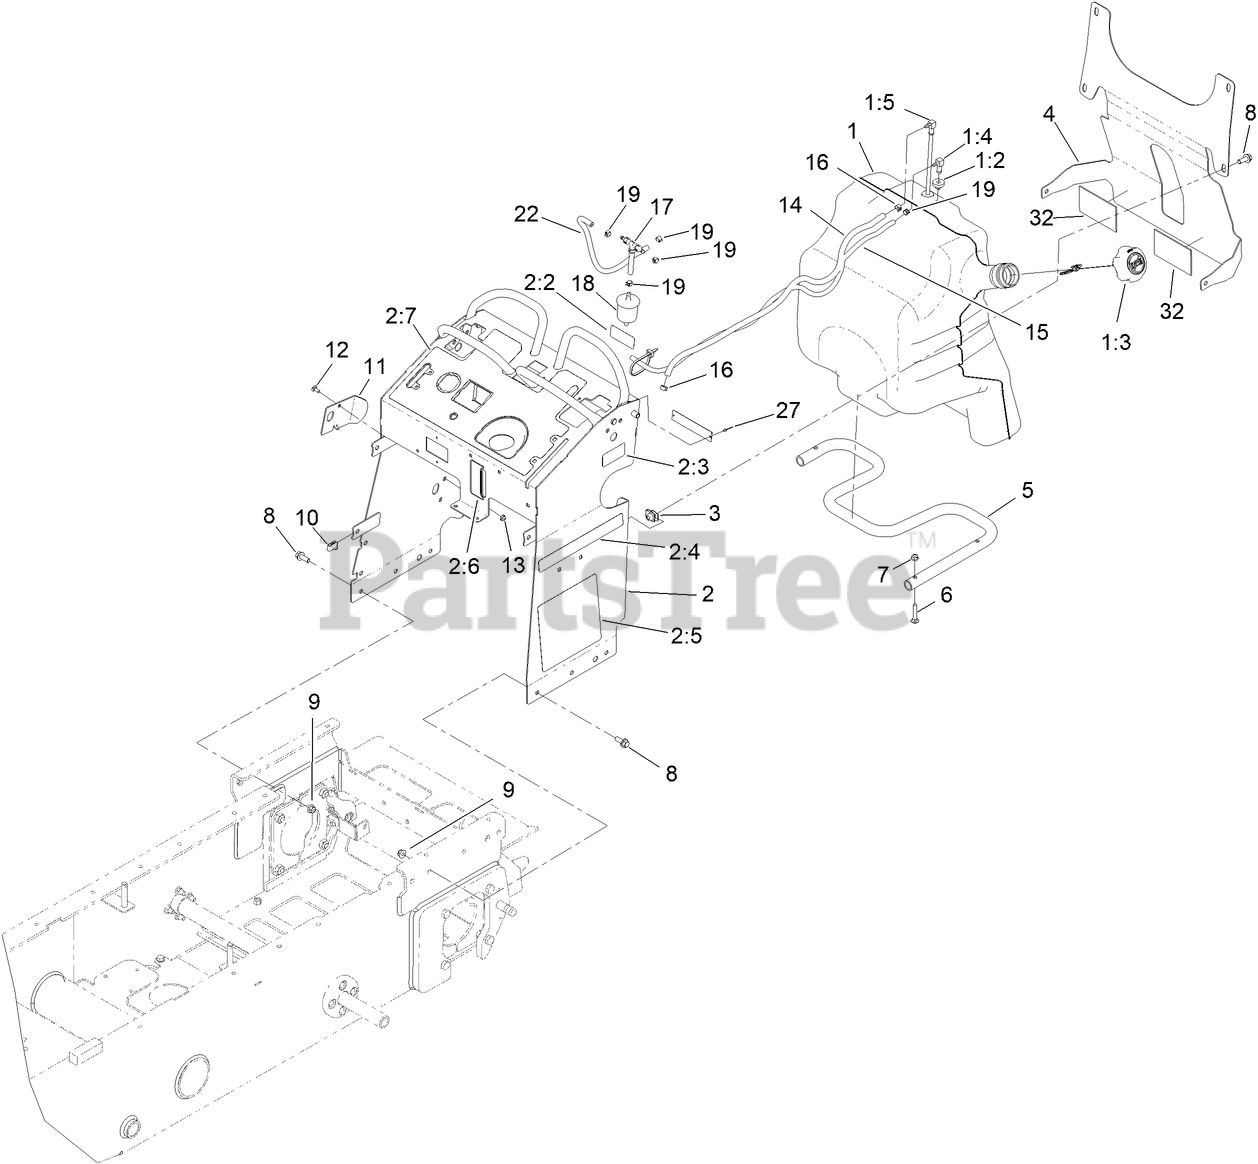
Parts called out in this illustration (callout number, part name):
1	FUEL TANK ASM
1:2	BUSHING
1:3	CAP-FUEL
1:4	FITTING-ELBOW, 90 DEG
1:5	ASM, TUBE-FUEL
2	TOWER ASM- SWIVEL
2:2	DECAL-FUSE
2:3	DECAL-FILL, FUEL
2:5	DECAL - SERVICE, MBTX-2500S
2:6	DECAL-LEVEL, OIL
2:7	DECAL-CONTROL PANEL
3	NUT-TINNERMAN
4	BRACKET-CROSS
5	TUBE-MOUNT, FUEL TANK
6	BOLT-CAR
7	NUT-HF, NI
8	SCREW-HHF
9	NUT-HF, NI
10	NUT-CLIP, U
11	PLATE-STRIKER
12	SCREW-CARR
13	NUT-HF
14	HOSE-FUEL
15	HOSE-FUEL
16	CLAMP-HOSE
17	TEE AND CHECK
18	FILTER-FUEL
19	CLAMP-HOSE
22	HOSE-VENT
32	PAD-FOAM
